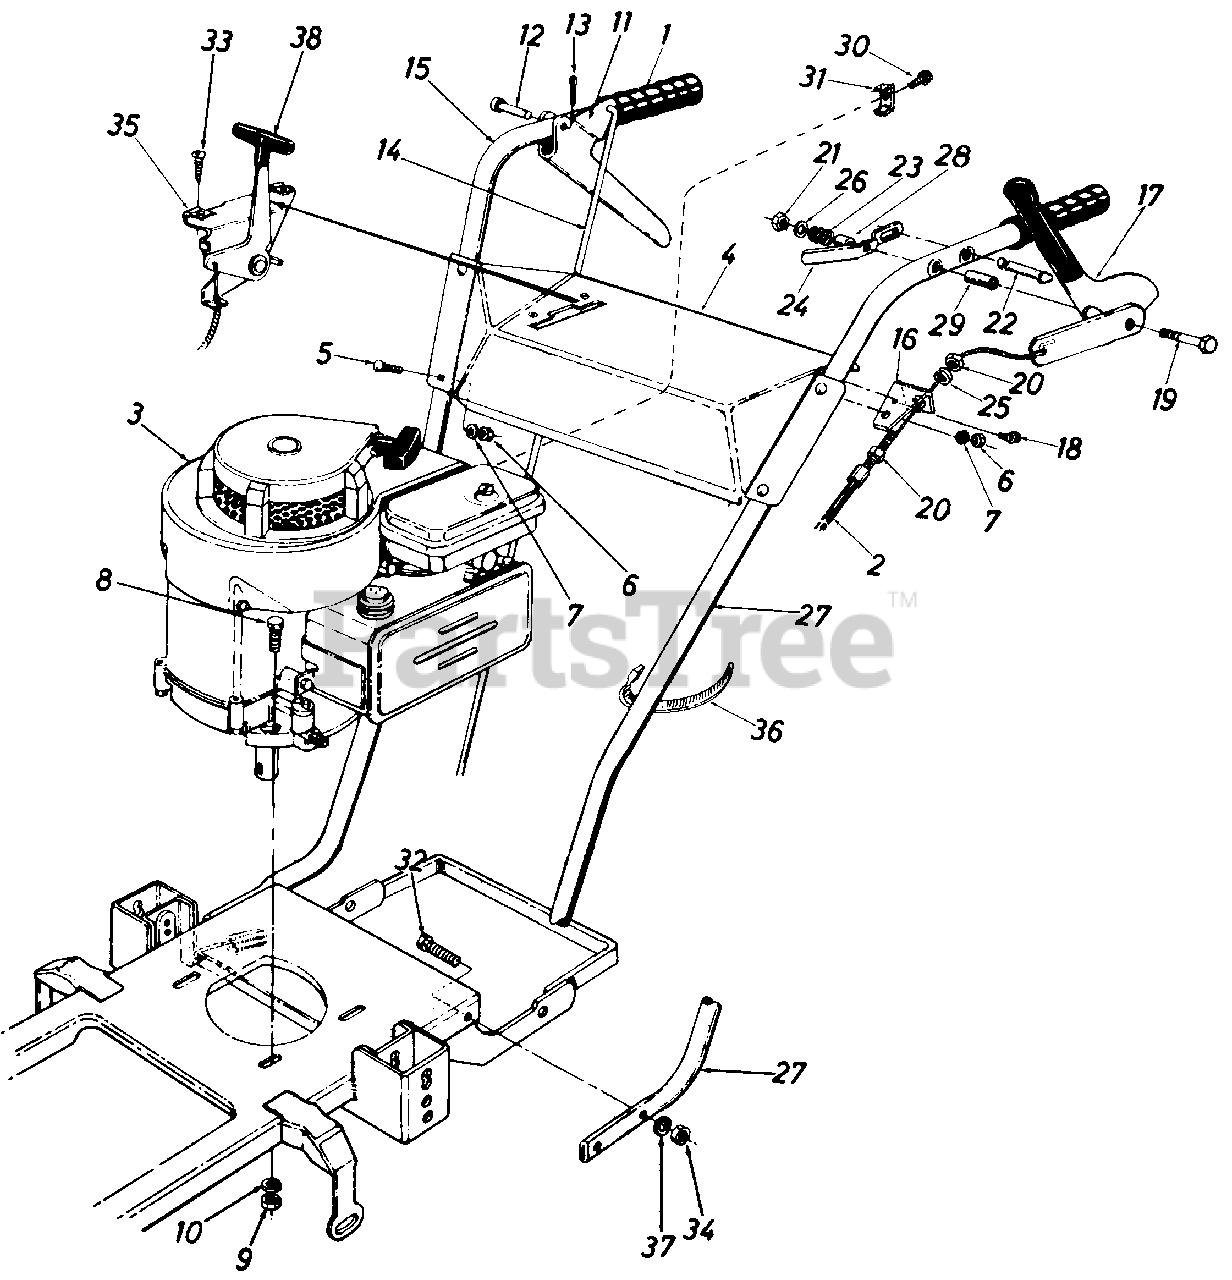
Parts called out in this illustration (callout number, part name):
2	Clutch Cable-39.0"
3	Engine
4	Handle Panel
5	Carr. Bolt 5/16-18 x 1.75" Lg.*
6	Hex Nut 5/16-18 Thd.
7	L-Wash. 5/16" I.D.
8	Hex Bolt 5/16-24 x 1.25" Lg.
9	Hex Nut 5/16-24 Thd.
10	L-Wash. 5/16" I.D.
11	Clutch Grip Ass'y.
12	Clevis Pin .375" Dia.
13	Intern. Cotter Pin 5/16" Dia.
14	Drive Control Rod
15	Handle-R.H.
16	Clutch Cable Brkt.
17	Blade Clutch Grip Ass'y.
18	Hex Wash. S-Tap Scr. 1/4-20 x.50" Lg.
19	Hex Bolt 1/4-20 x 2.25" Lg.
20	Hex Jam Nut 5/16-24 Thd.
21	Hex Cent. L-Nut 1/4-20 Thd.
22	Lock Pin
23	Compression Spring
24	Lockout Spring
25	L-Wash. 5/16" I.D.
26	Internal Tooth L-Wash.
27	Handle-L.H.
28	Spacer.44" Lg.
29	Spacer 1.03" Lg.
30	Hex AB-Tap Scr. #10 x .38" Lg.
31	Casing Clamp
32	Hex Bolt 5/16-24 x 1.25" Lg.
33	Hex Wash. Hd. AB-Tap Scr. #10 x .50" Lg.
34	Hex Nut 5/16-24 Thd.
35	Speed Nut 10Z U-Type
36	Cable Tie
37	L-Wash. 5/16" I.D.
38	Throttle Control
